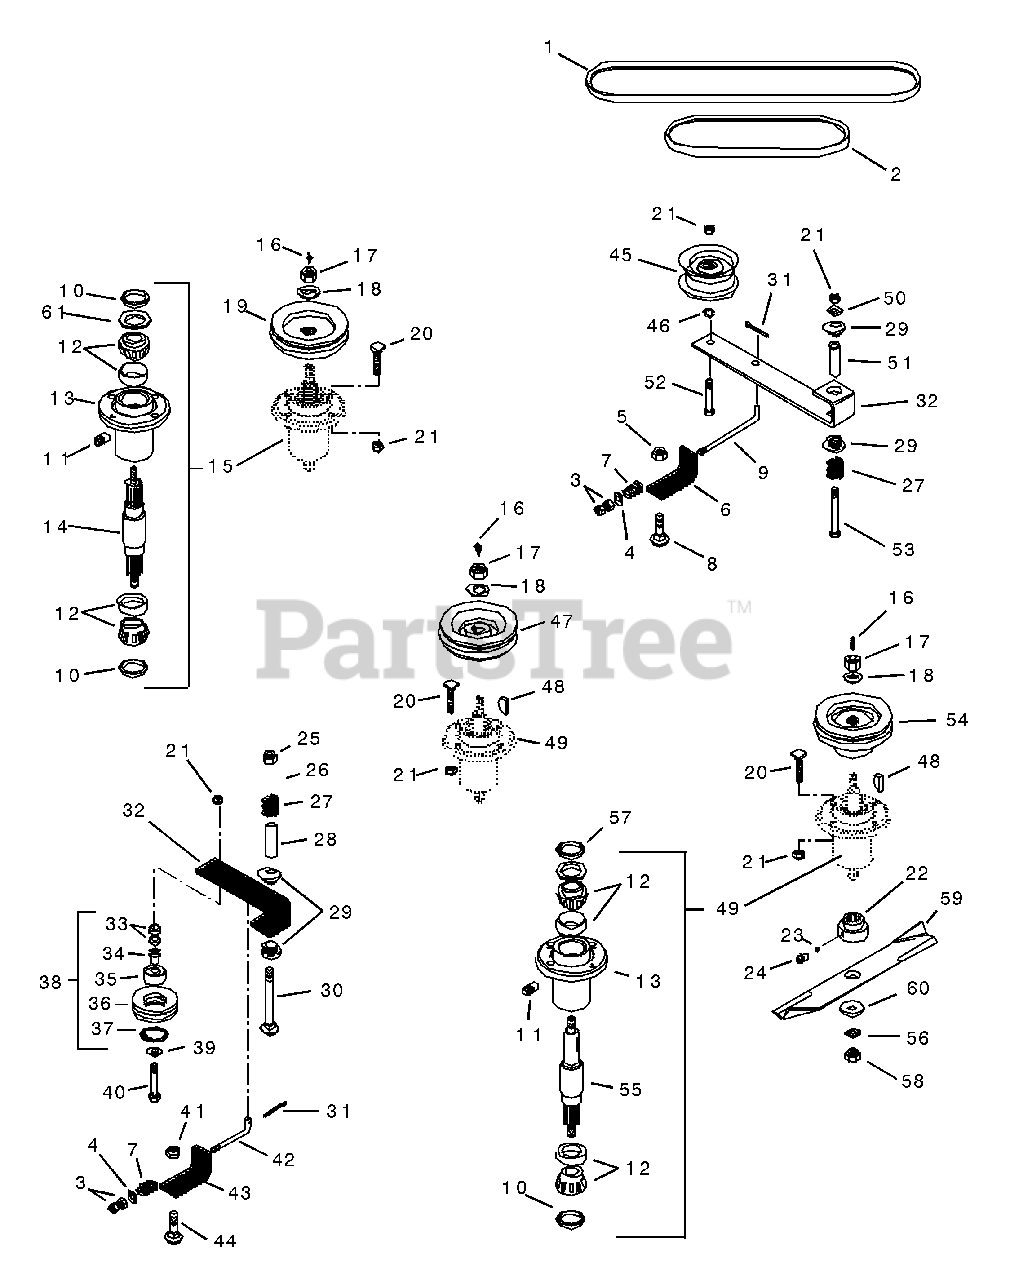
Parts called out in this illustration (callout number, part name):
1	V-Belt
2	Belt, Mower A44
3	Nut-Hex .375-24
4	Washer-Flat-Steel .406 x .812 x .065
5	Nut-Locking-Nylon .312-18 w/Insr Grade 2
6	Bracket, Belt Tensioner
7	Spring-Compression .125 x .781 x 1.00 338 lbs/in
8	Bolt, Round Head Square Neck .31-18 x 1.0
9	Rod, Idler 50 Inch Mower
10	Seal 1.987 x 1.375 x .313
11	Relief Fitting, Grease
12	Assembly, Bearing Cup and Cone
13	Bearing Housing
14	Shaft, Spindle
15	Service Kit, Spindle Assembly
16	Fitting, Lube 1/8
17	Nut-Locking-Nylon .625-11 Grade 2
18	Washer-Flat-Steel .687 x 1.312 x .135
19	Sheave
20	Bolt, Round Head Square Neck .31-16 x 1.375
21	Nut-Locking-Nylon .375-16 w/Insr Grade 2
24	Screw-Set .25-20 x .25
25	Nut-Locking .50-13
26	Washer-Flat-Steel .531 x 1.250 x .100
27	Spring-Compression .085 x .80 x 1.00
28	Spacer, .560 x .750 x 2.437 Steel
29	Bushing-Flange .764 x 1.47 x .560 Nylon
30	Bolt, Round Head Square Neck .50-13 x 3.50
31	Pin, Cotter .09 x 1.00
32	Arm, Idler Pivot
33	Bushing .406 x .750 .188
34	Bushing-Flange .786 x 1.0 x .79
35	Bearing-Ball 1.85 x .787 x .55
36	Sheave, Idler
37	Ring-Retaining-Internal 2.054 x .062
38	Assembly, Idler Sheave
39	Washer-Flat-Steel .375 x 1.125 x .065
40	Bolt-Hex .38-16 x 2.00 Grade 5
41	Nut-Locking-Nylon .50-13 Grade 5
42	Rod, Idler
43	Bracket, Tensioner
44	Bolt, Round Head Square Neck .31-18 x 1.50
45	Bracket, Belt Tensioner
46	Bushing-Flange .406 x .88 x .270 x .140
48	Key, Woodruff .25 x 1 Hard #15
49	Service Kit, Spindle Assembly
50	Washer-Flat-Steel .438 x 1.000 x .083
51	Bushing, Steel .437 x .750 x 2.44
52	Bolt-Hex .28-16 x 2.25 Grade 5
53	Bot-Hex .38-16 x 3.25 Grade 5
54	Sheave
55	Shaft, Spindle
56	Washer-Lock .625 x .156
57	Seal 1.987 x 1.500 x .313
58	Nut-Hex .625-11 Grade 2
59	Blade
60	Washer
61	Washer-Flat-Steel 1.007 x 1.542 x .062
